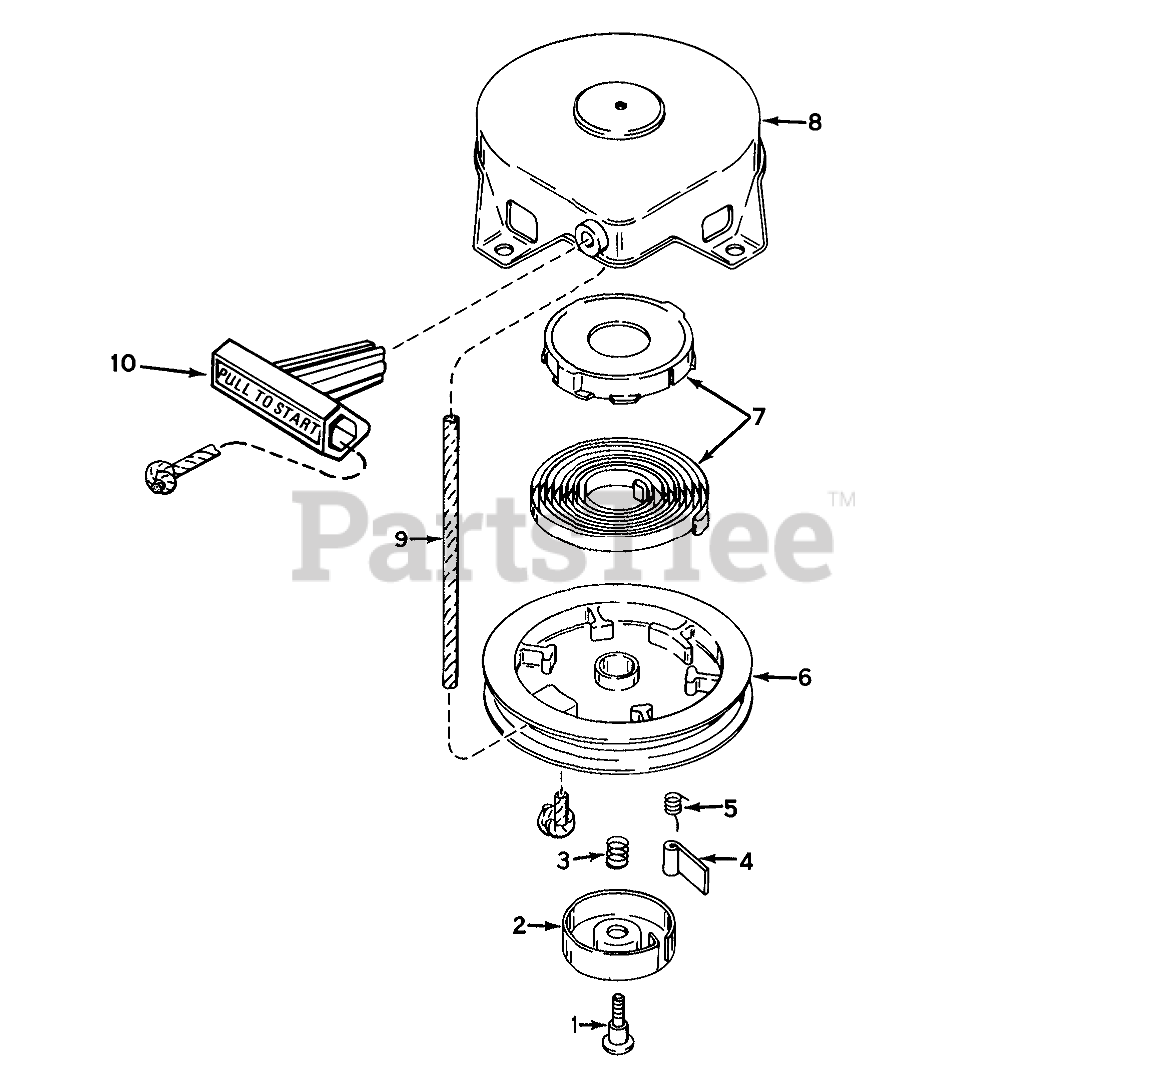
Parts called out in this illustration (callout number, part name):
2	Retainer
3	Spring-Brake
4	Dog-Starter
5	Spring-Dog
7	Spring & Keeper Assy
8	Housing-Starter
9	Rope-Starter (98 cut to length)
10	Handle-Starter
